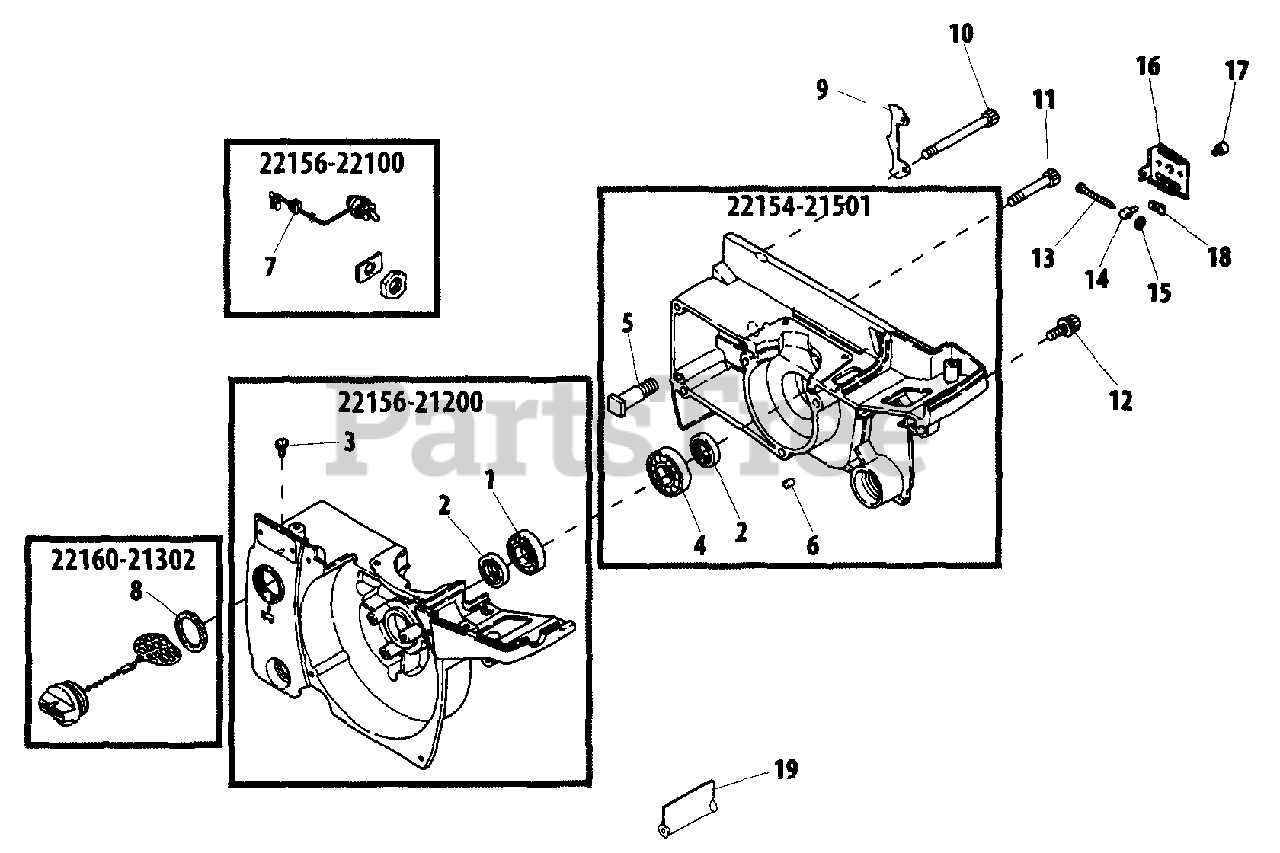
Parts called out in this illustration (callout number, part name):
1	BEARING, BALL - 6001C3
2	SEAL, OIL
3	VALVE, OIL
4	BEARING, BALL - 6201C3
5	STUD, GUIDE BAR
6	PIN - LOCATING
8	GASKET
9	SPIKE
10	SCREW - 5X45
11	SCREW - 5X30
12	SCREW - 5X18
13	SCREW, ADJUST
14	TENSIONER, CHAIN
15	NUT
16	GUARD, MOUNT
17	BAR PIN
18	GUIDE, CHAIN
22154-21501	CRANKCASE ASSY - RIGHT
22156-21200	CRANKCASE ASSY - LEFT
22156-22100	IGNITION SWITCH ASSY
22160-21302	CAP ASSY
